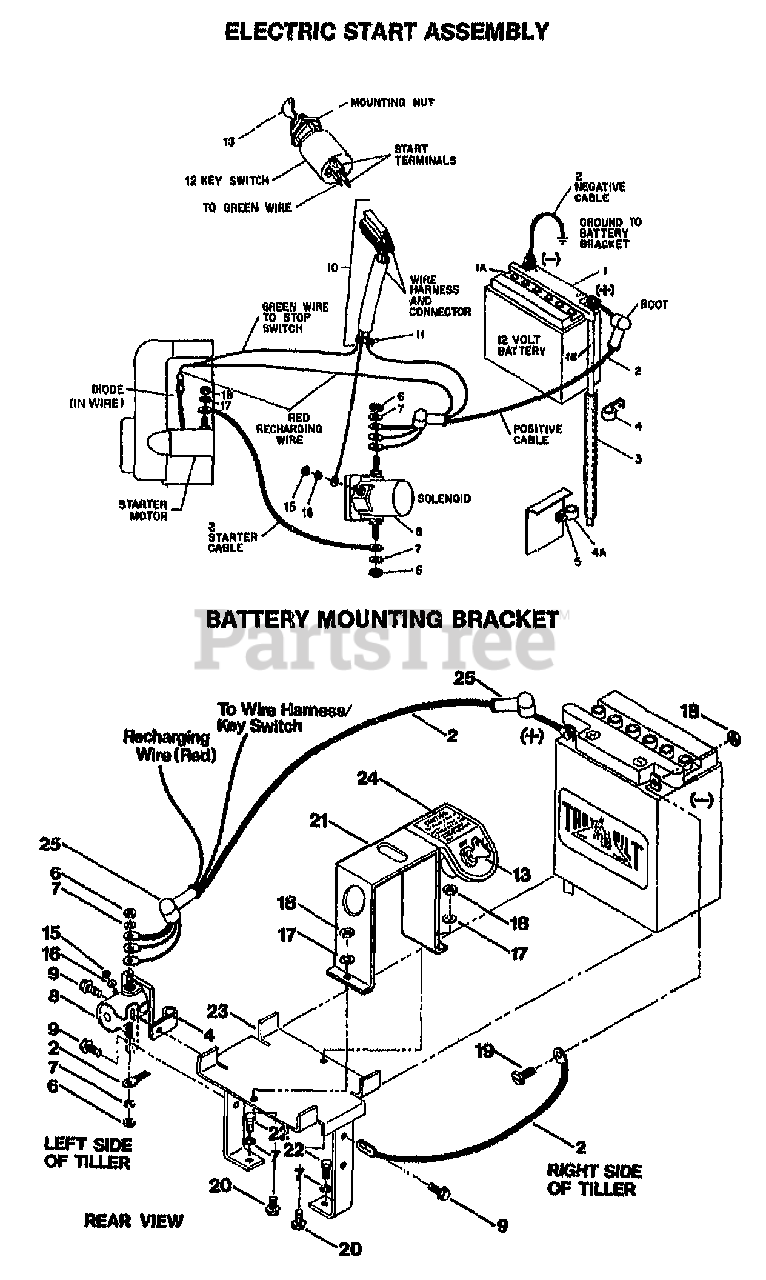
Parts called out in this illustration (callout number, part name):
1	BATTERY 12 volt, 12amp.
1A	CAP-YELLOW
1A	CAP-BATTERY WHITE (PONY)
1B	TUBE-VENT BATTERY/HSE
2	CABLE-BATT. (Pos./ Neg. batt. & strtr cables)
3	TUBING-RUBBER
4	CLAMP (Small vent tube shield)
4A	CLAMP (Large vent tube shield)
5	SCR-HHC 5/16-18X.75 GR 5 ZP
6	NUT-HEX 5/16-24
7	WASHER-LK .312 ZP
8	KIT-SOL W/HDW
9	SCR-HWH 1/4-20 X .5 STH
10	HARNESS-WIRE 6HP
11	TIE-TWIST LOCK
12	KEYSWITCH W/KEYS
13	KEYS(1 PAIR) FOR SWITCH
15	NUT-HH M10-32X.125
16	WASHER-EXTERNAL TOOTH 1
17	WASHER-LK .25 ZP
18	NUT-HEX 1/4-20 ZP
19	BOLT-SLHH 1/4-20 X .5
20	SCR-CARR 1/4-20X1.25
21	PLTE-KEYSWITCH W/DEC-PONY 3
22	SCR-HH 5/16-18X1.0 G5 ZP
23	BRKT-BATTERY PNT
24	DECAL-KEYSWITCH TILLER
